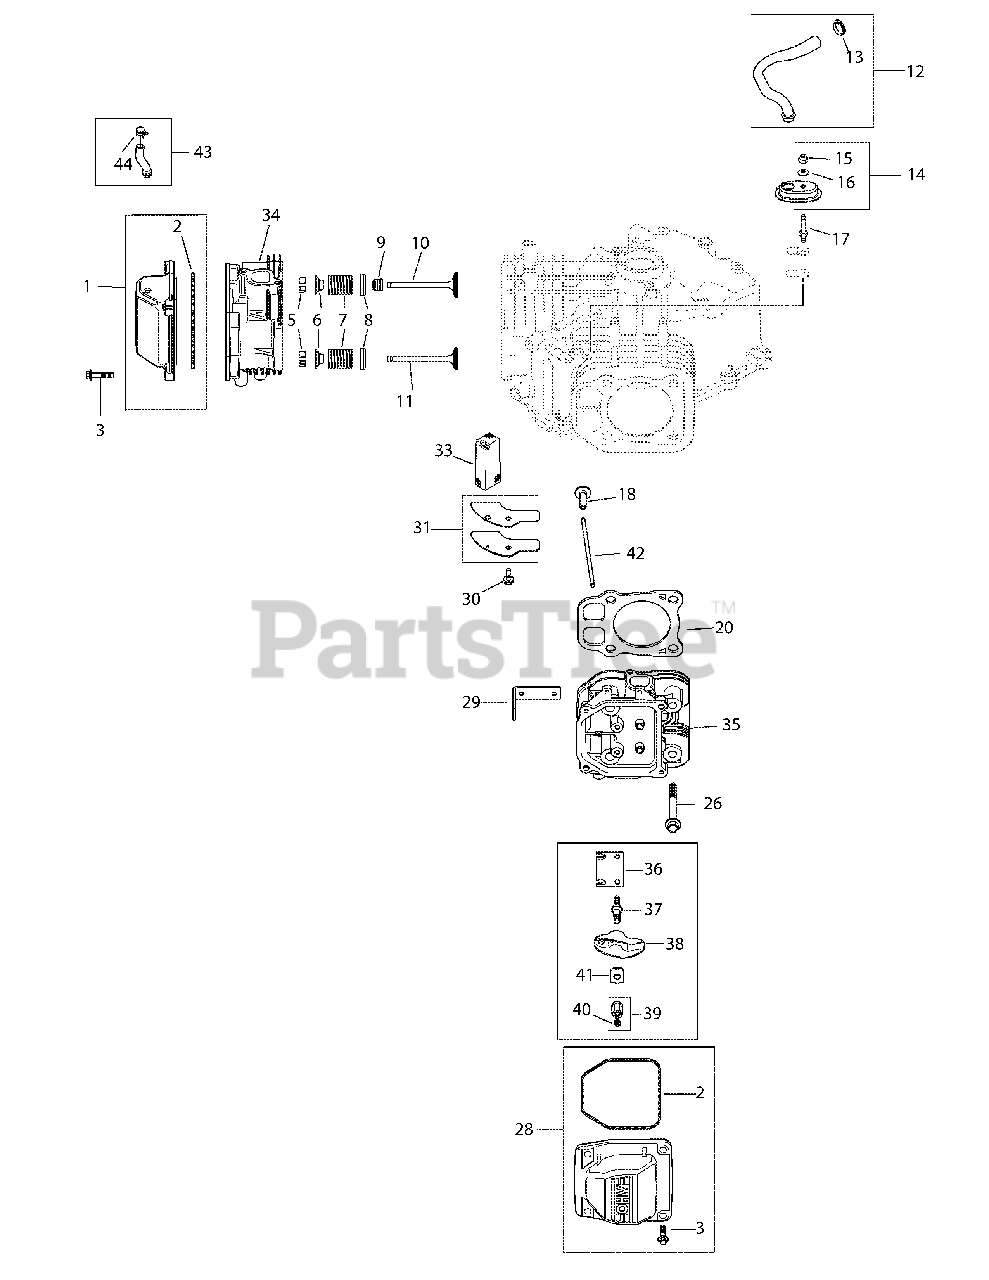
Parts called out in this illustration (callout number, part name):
1	Breather Valve Cover Kit (Inc. 2)
2	Valve Cover O-Ring
3	Flg. Screw, M6 X 1.0 X 30
5	Retainer Kit
6	Valve Spring Cap
7	Valve Spring
8	Spring Retainer
9	Valve Stem Seal
10	Intake Valve (Std)
11	Exhaust Valve (Std)
12	Kit, Breather Hose Kit (Inc. 13)
13	Hose Clamp, 1/2
14	Breather Housing Kit (Inc. 15, 16)
15	Lock Nut, M 5 X .8
16	Sealing Washer
17	Breather Cover Stud
20	Cylinder Head Gasket Kit
26	Flg. Screw, M 10 X 1.5 X 90
28	Breather Valve Cover Kit (Inc. 2 & 3)
29	Lifting Strap
30	Flg. Thd. Frm. Screw, M6 X 1.0 X 16
31	Breather Cover Kit (Inc. 32)
33	Breather Filter
34	#1 Cylinder Head Assembly Kit
35	#2 Cylinder Head Assembly Kit
39	Hex Nut Assembly (Includes 39)
41	Rocker Arm Pivot
43	Fuel Pump Hose w/ Clamp Kit (Inc. 44)
